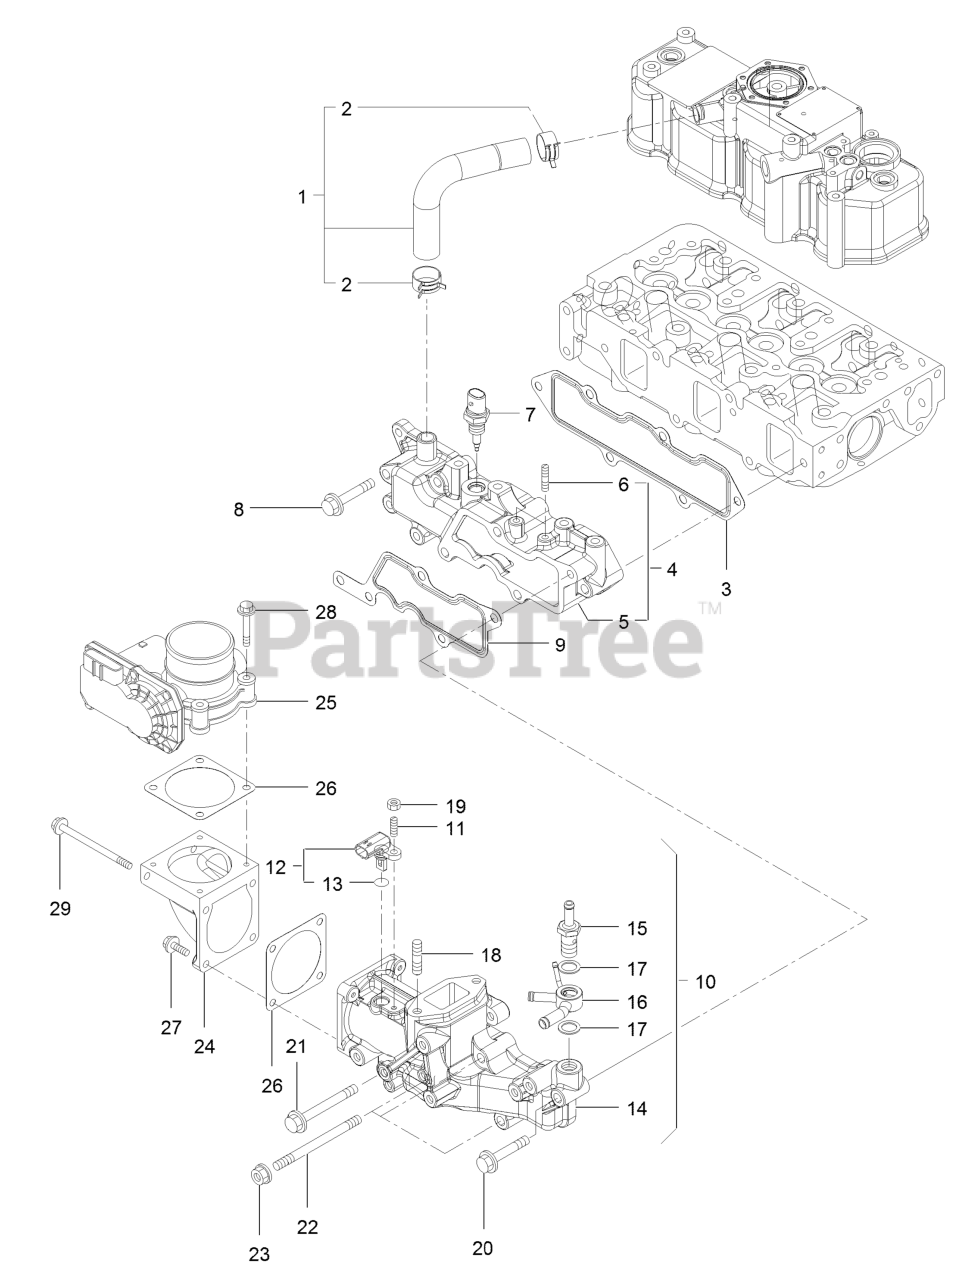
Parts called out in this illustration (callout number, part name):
2	Clip-Hose
3	Gasket-Manifold, Intake
4	Intake Manifold ASM
5	Manifold-Intake
7	Sensor-Temp, Air
9	Gasket-Collector
10	Intake Collector ASM
12	Sensor-Temp, Air
13	O Ring-Sensor, Temp
14	Collector-Intake
15	Joint-Hose
16	Joint-Hose
17	Washer-Seal
24	Bend-Inlet
25	Body-Throttle
26	Gasket-Throttle
